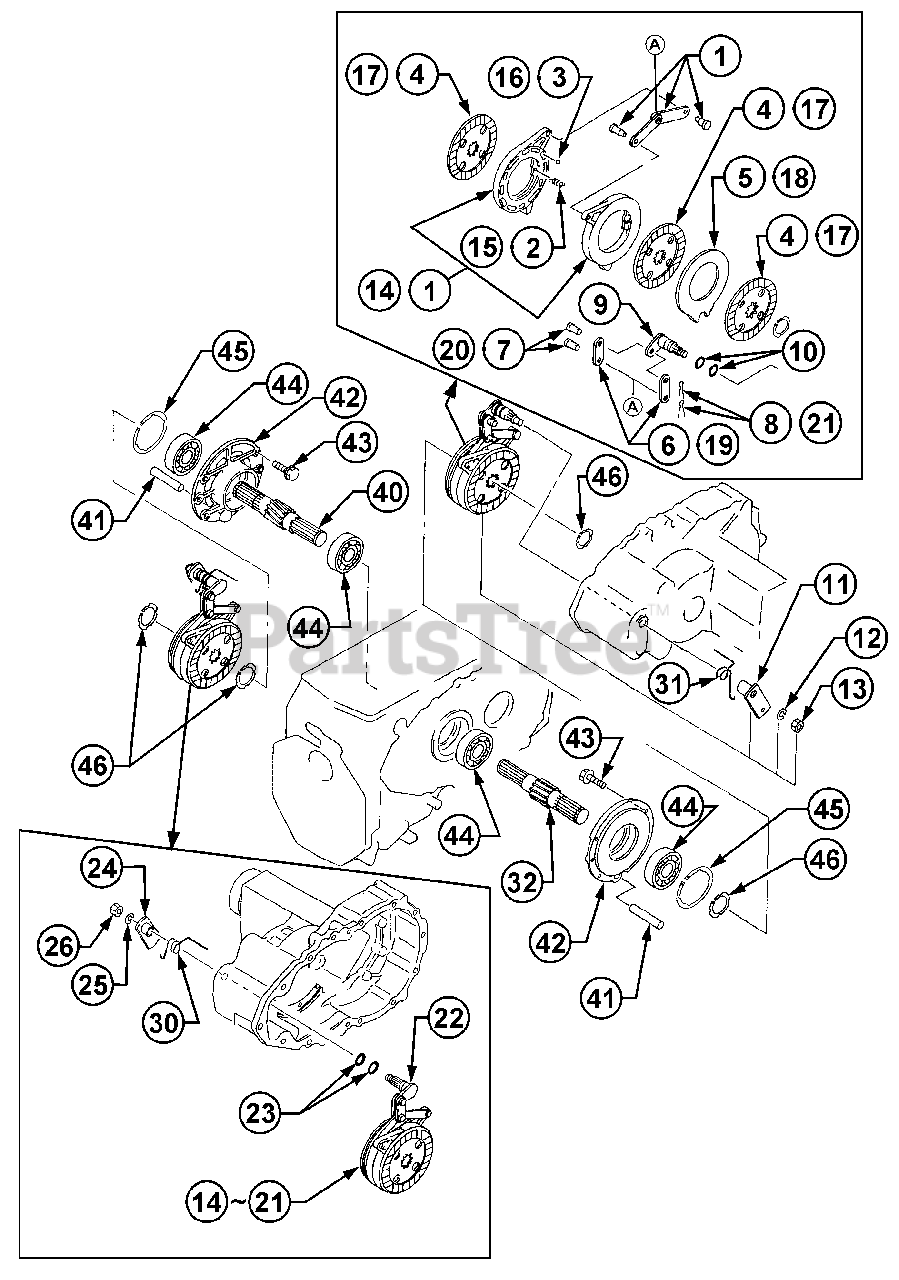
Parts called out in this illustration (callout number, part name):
5	Plate, Mating
12	Washer, Spring
18	Plate, Mating
25	Washer, Spring
43	Bolt
44	Bearing, Ball
